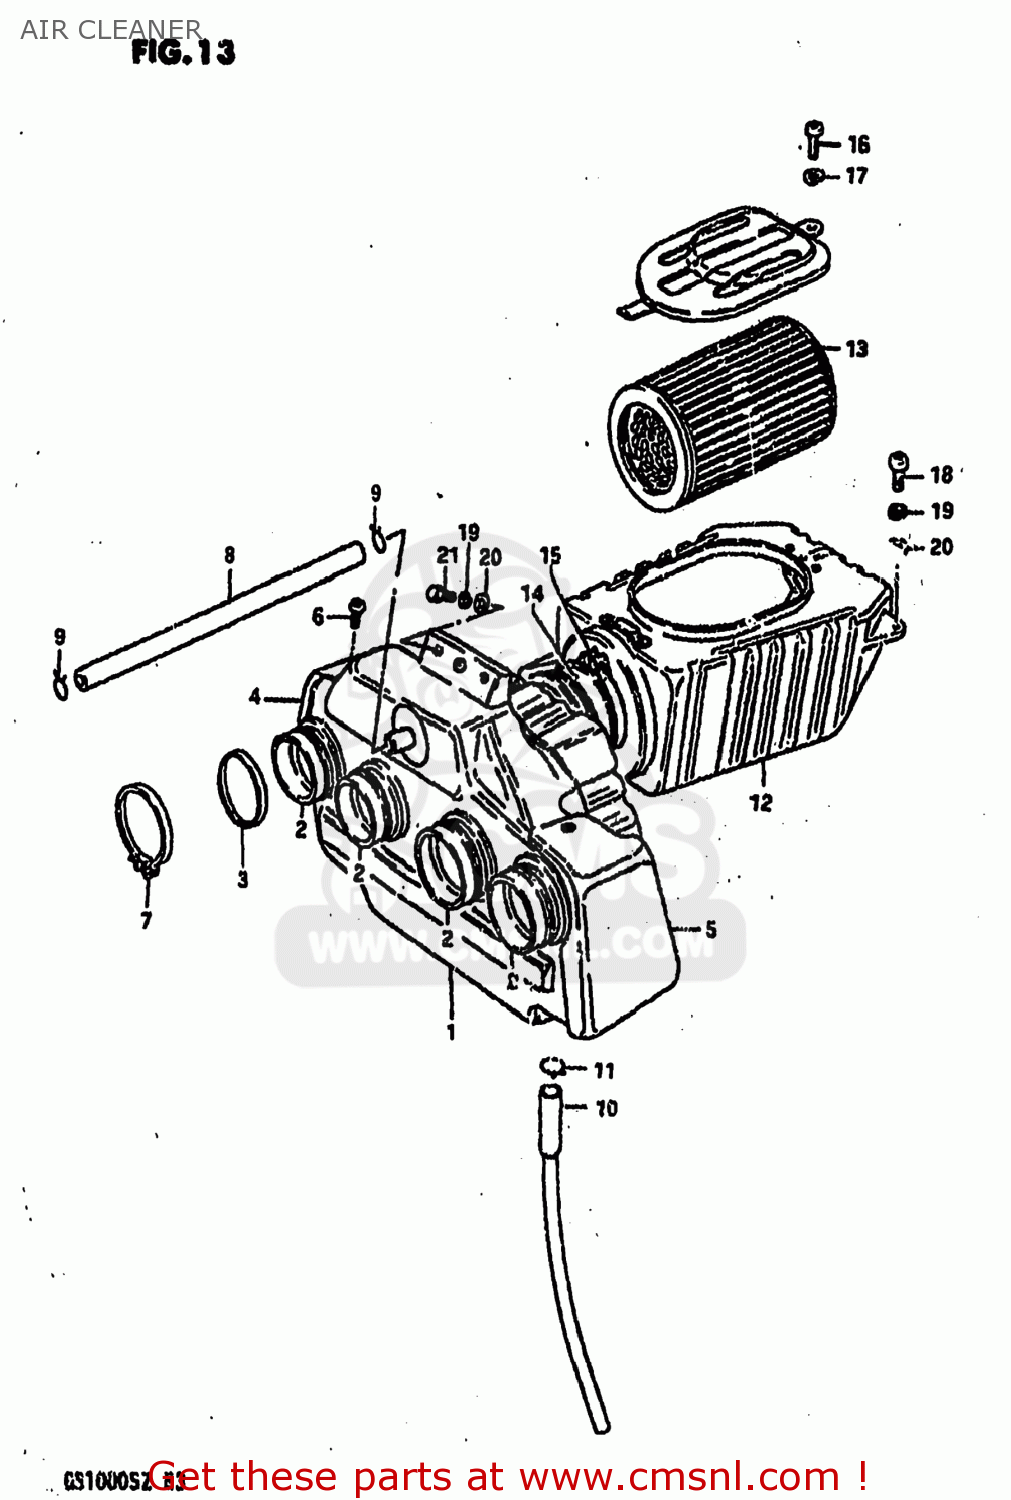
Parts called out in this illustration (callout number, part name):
1	CASE ASSY, FRONT
2	TUBE,AIR CLEANER OUTLET
3	RING,CARBURETOR AIR INLET HOSE
4	COVER,AIR CLEA
5	COVER
6	SCREWM4X0.7X10
7	CLAMP
8	TUBE,BREATHER
9	CLIP
10	DRAIN TUBE
11	CLIP
12	CLEANER SET,AIR,REAR
13	FILTER,AIR CLEANER
14	HOSE,AIR CLEANER
15	BAND
16	SCREW
17	LOCK WASHER
18	SCREW
19	LOCK WASHER
20	WASHER
21	BOLT
